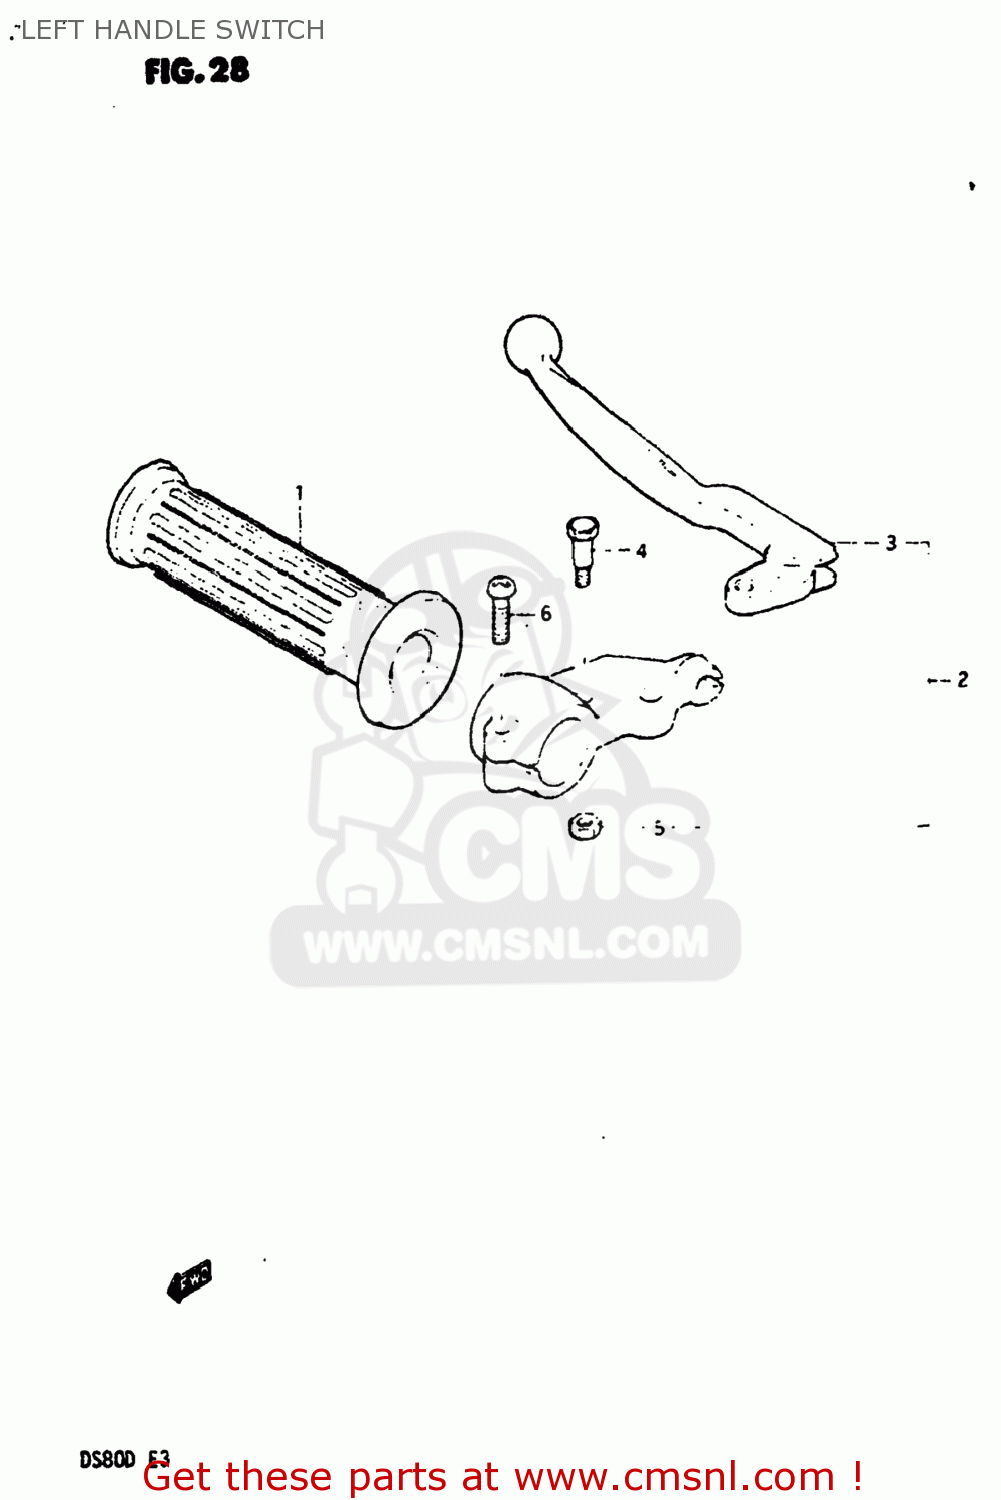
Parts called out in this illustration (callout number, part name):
1	GRIP,LEFT
2	LEVER ASSY,CLUTCH
3	LEVER,CLUTCH
4	BOLT,LEVER
5	NUT
6	SCREW
